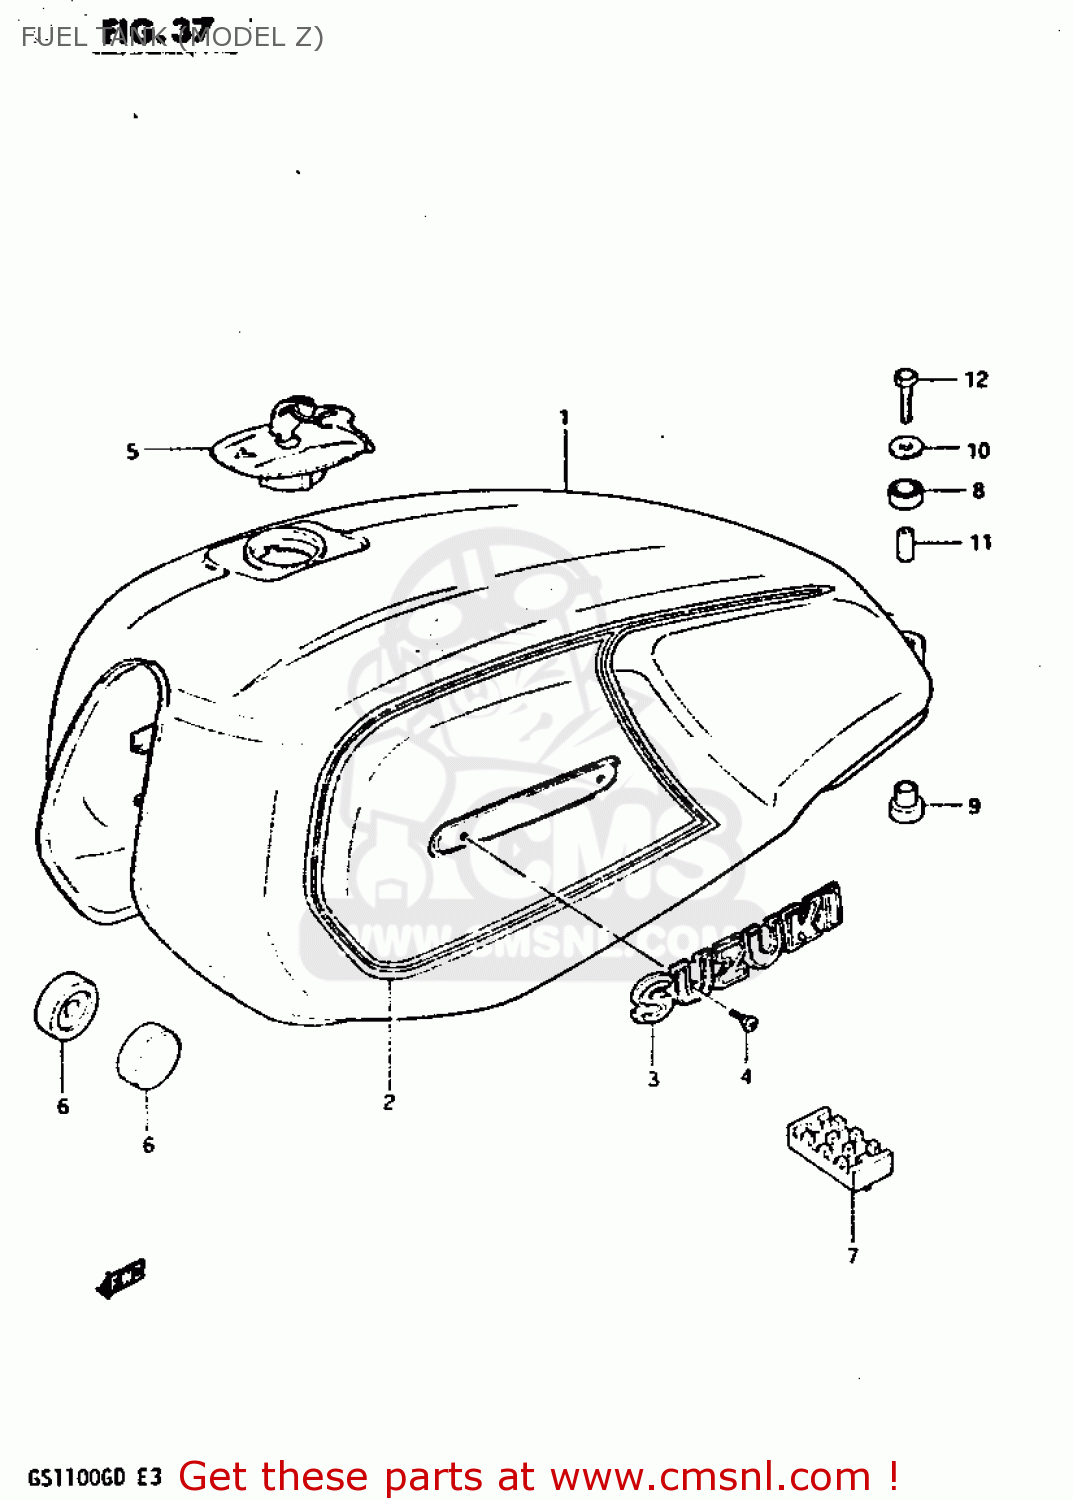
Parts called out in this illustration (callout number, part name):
1	TANK ASSEMBLY,FUEL
2	TAPE SET,FUEL TANK
3	EMBLEM
4	SCREW 3X6
5	CAP SET,FUEL TANK
6	CUSHION
7	CUSHION,FUEL TANK
8	CUSHION
9	CUSHION
10	WASHER (6.5X24X1.6)
11	SPACER (6.4X9X21.5)
12	BOLT
